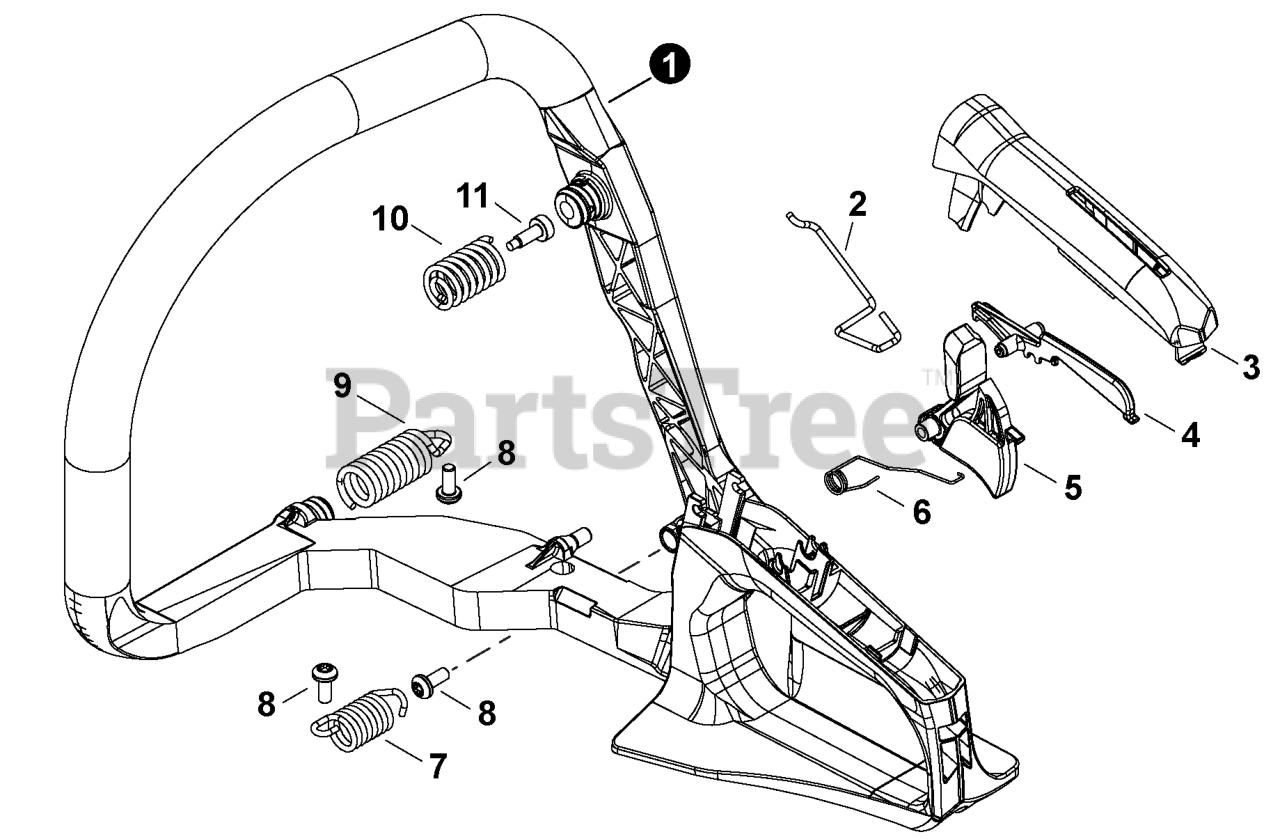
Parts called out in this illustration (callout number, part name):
1	HANDLE, FRONT & REAR
2	ROD, THROTTLE
3	COVER, HANDLE
4	LEVER, THROTTLE LOCKOUT
5	TRIGGER, THROTTLE
6	SPRING, TORSION
7	SPRING, COMPRESSION
8	BOLT, TORX 5x12
9	SPRING, COMPRESSION
10	SPRING, COMPRESSION
11	BOLT, TORX 5x16
